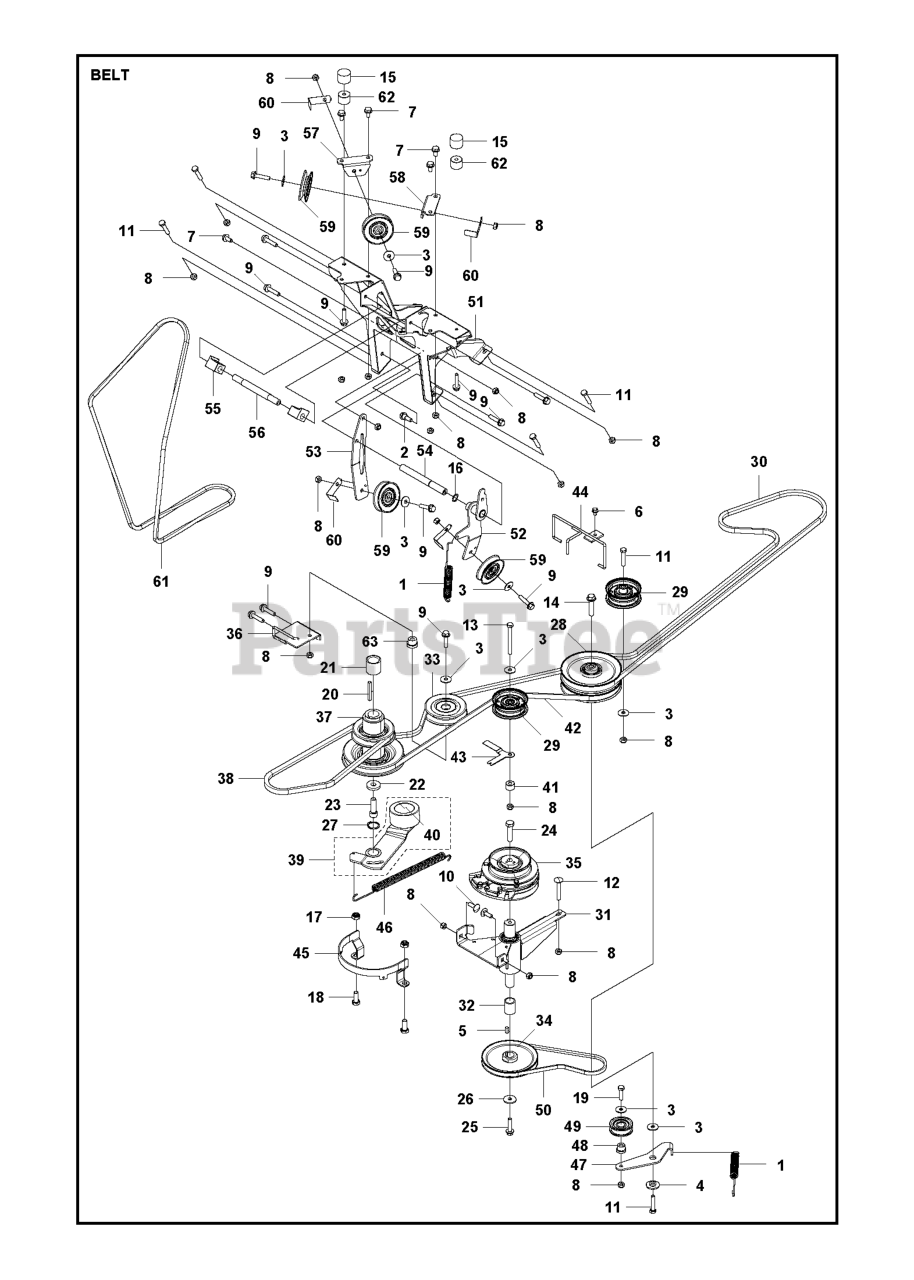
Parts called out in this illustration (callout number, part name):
4	WASHER
8	LOCKNUT M8
9	SCREW EHHFM
14	COLLAR SCREW
15	ANTIVIBRATION ELEMENT
16	RETAINING RING SGA 15
17	NUT
18	Screw M10x25
27	RETAINING RING SGA 25
29	IDLER PULLEY
